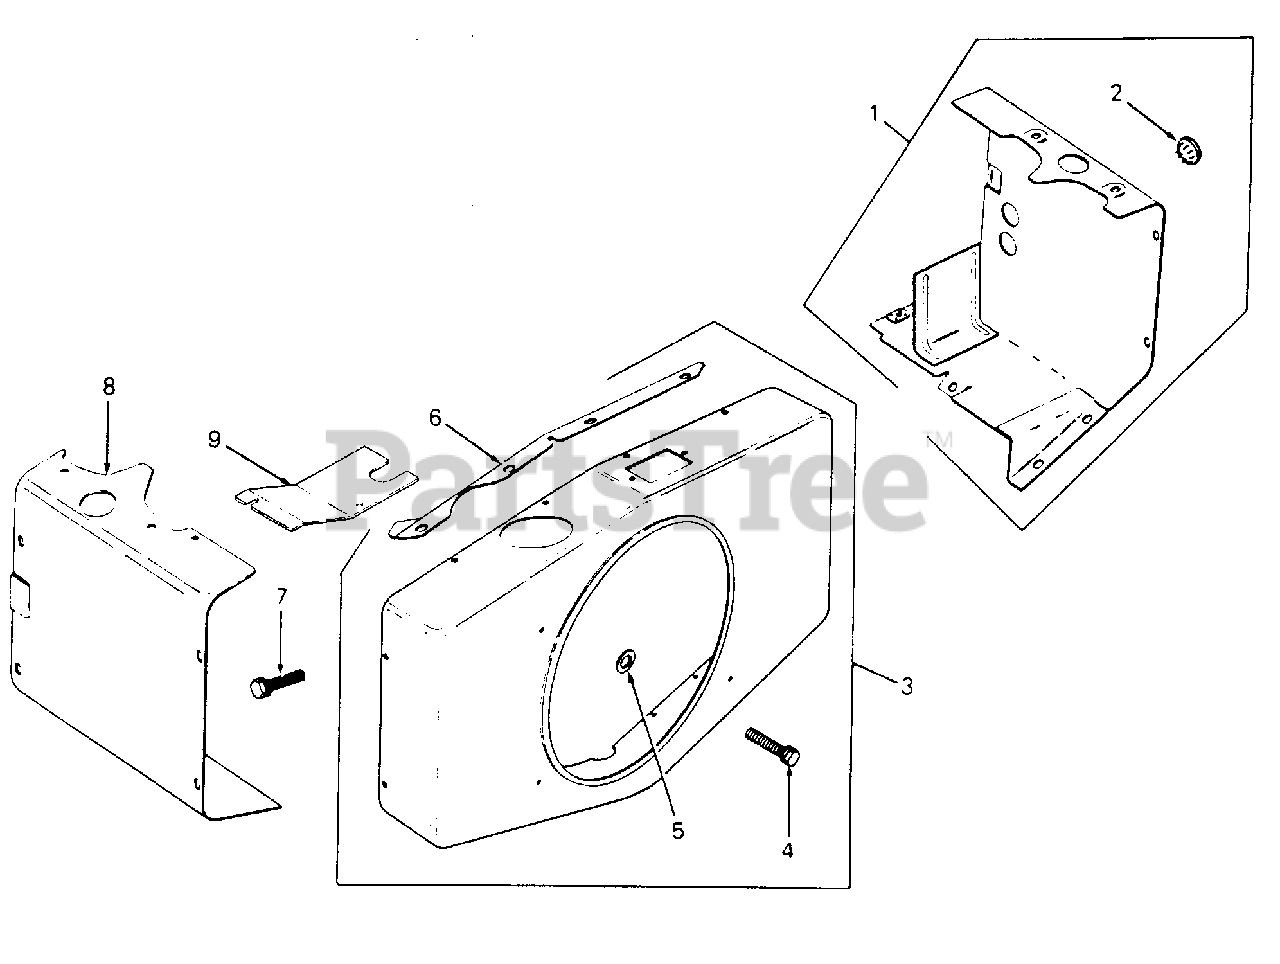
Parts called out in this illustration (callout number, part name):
1	Kit, #1 Cylinder Head Baffle
2	Plug, Button
3	Kit, Blower Housing
4	Screw, Self Tap, 1/4-20 X .62 Lg
5	Washer, Flat, 1/4
6	Support, Upper Housing
7	Screw, Hex Wash Hd, 1/4-20 X .43 Lg
8	Baffle, #2 Cylinder Head
9	Baffle, #2 Cylinder Top
